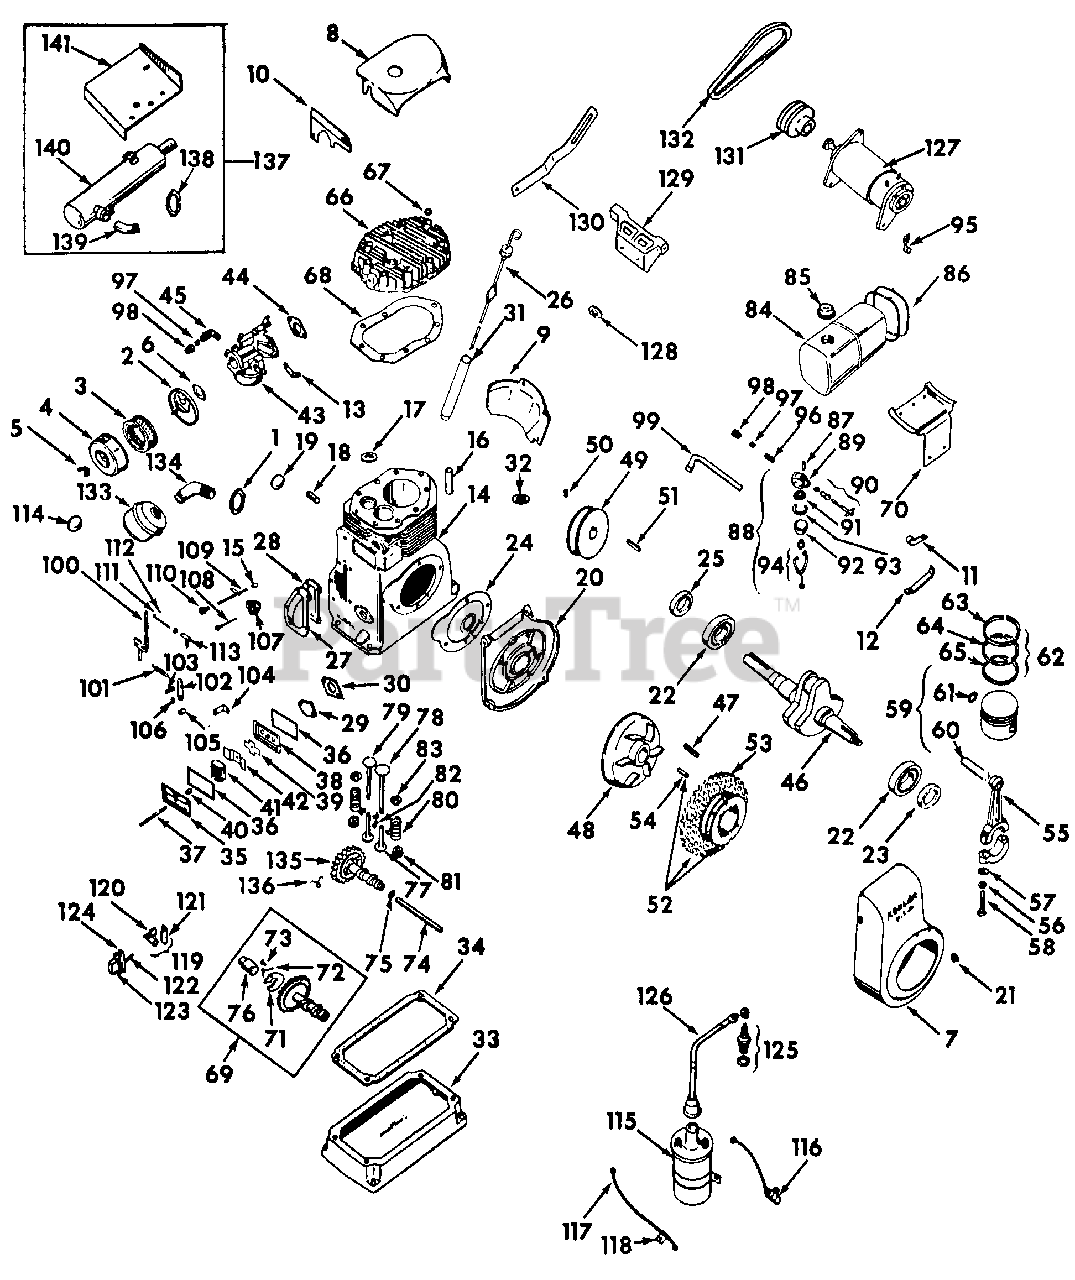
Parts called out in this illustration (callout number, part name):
1	Nut, Exhaust Muffler Elbow Lock
2	Base, Air Cleaner
3	Element, Air Cleaner Filter
4	Cover, Air Cleaner
5	Nut, Air Cleaner Wing
6	Gasket, Air Cleaner
7	Housing Assembly, Blower
8	Baffle, Cylinder Head Air
9	Baffle, Cylinder Air
10	Baffle, Housing Side Air
11	Clip, Choke Cable
12	Bracket, Throttle Cable
13	Bracket, Choke
14	Crankcase Assy
15	Bearing, Needle
16	Guide, Valve
17	Insert, Exhaust Valve
18	Shaft, Governor
19	Plug, 1-1/8 Expansion, Crankcase
20	Plate, Crankcase Brg
21	Plug, 5/8 Button, Crankcase Bearing Plate
22	Bearing, Crankcase Ball
23	Seal, Crankcase Brg Plate Oil
24	Gasket, Brg Plate
25	Seal, Crankcase Oil
27	Cover, Camshaft
28	Gasket, Camshaft Cover
29	Cover, Fuel Pump Pad
30	Gasket, Fuel Pump Pad Cover
31	Tube, Oil Fill
32	Insert, Intake Valve
33	Base, Oil Pan
34	Gasket, Oil Pan Base
35	Cover, Breather
36	Gasket, Breather
37	Stud, Breather Cover
38	Plate, Breather
39	Reed, Breather
40	Seal, Breather
41	Filter, Breather
42	Baffle, Breather
43	Carburetor Assy
44	Gasket, Carburetor
45	Elbow, Carburetor to Fuel Line
47	Key, Crankshaft
49	Pulley w/Clutch Drive Plate, Flywheel
50	Screw, Flywheel Pulley Set
51	Key, 1/4 X 7/8 Sq Parallel
52	Cup Assy, Flywheel Drive
53	Screen, Drive Cup Grass
54	Pin, Flywheel Drive Cup
55	Rod Assy, Connecting, Std
56	Washer, Connecting Rod Lock
57	Washer, Connecting Rod
58	Screw, Connecting Rod
59	Piston Assy, Std
60	Pin, Piston, Std
61	Retainer, Piston Pin
62	Ring Set, Piston, Std
63	Ring, Compression
64	Ring, Center Compression
65	Ring, Oil Control
66	Head, Cylinder
67	Washer, Cylinder Head
68	Gasket, Cylinder Head
69	Camshaft Assy
70	Bracket, Fuel Tank
71	Flyweight, Camshaft
72	Spring, Spark Advance
73	Pin, Camshaft Flyweight
74	Pin, Camshaft
75	Shim, Camshaft, .005
76	Cam, Ignition
77	Tappet Assy, Valve
78	Valve, Intake
79	Valve, Exhaust
80	Spring, Valve
81	Retainer, Valve Spring
82	Key, Valve Spring Retainer
83	Retainer, Valve Spring Upper
84	Tank Assy, Fuel w/Filler Cap
85	Cap, Fuel Filler
86	Strap, Fuel Tank
87	Nipple, 1/8 X 3/4 C-Z Pipe
88	Filter Assy, Fuel
89	Body, Fuel Filter
90	Valve Assy, Needle
91	Screen, Filter
92	Bowl, Fuel Filter Glass
93	Gasket, Fuel Filter Bowl
94	Bail Assy, Fuel Filter Bowl
95	Clip, Cable Harness
96	Connector, Fuel Filter
97	Sleeve, Fuel Line
98	Nut, Fuel Line
99	Line, Fuel Filter to Carburetor Fuel
100	Lever, Governor
101	Spring, Governor
102	Bracket, Speed Control
103	Clamp, Control Bracket
104	Bracket, Adjusting Screw
105	Spacer, Adjusting Screw
106	Washer, Adjusting Screw Spacer
107	Gear Assy, Governor
108	Pin, Governor Stop
109	Shaft Assy, Governor Cross
110	Bushing, Cross Shaft
111	Rod, Ball Joint Throttle
112	Retainer, Throttle Rod
113	Joint, 10-32 X 1/4 Ball
114	Plug, 1-1/8 Expansion
115	Coil, Ignition
116	Condenser, Ignition Coil
117	Cable Assy, Condenser to Breaker
118	Clip, Condenser to Breaker Cable
119	Bracket & Breaker Assy
120	Breaker Point Set
121	Bracket, Point Breaker
122	Rod, Breaker
123	Cover, Breaker
124	Gasket, Breaker Cover
125	Plug, Spark (Champion)
126	Kit, Hi-Tension Spark Plug Cable Lead
127	Motor Generator
128	Shim, Motor Generator Mounting Bolt
129	Bracket, Motor Generator Mounting
130	Brace, Motor Generator Adjusting
131	Pulley, Motor Generator Drive
132	Belt, Motor Generator Drive
133	Muffler, Exhaust
134	Tube, Exhaust Muffler
135	Camshaft Assy
136	Spring, Camshaft Actuating
137	Parts Accessory, Muffler & Heat Shield
138	Nut, Exhaust Muffler Elbow Lock
139	Tube, Exhaust Muffler
140	Muffler, Exhaust
141	Baffle, Heat
